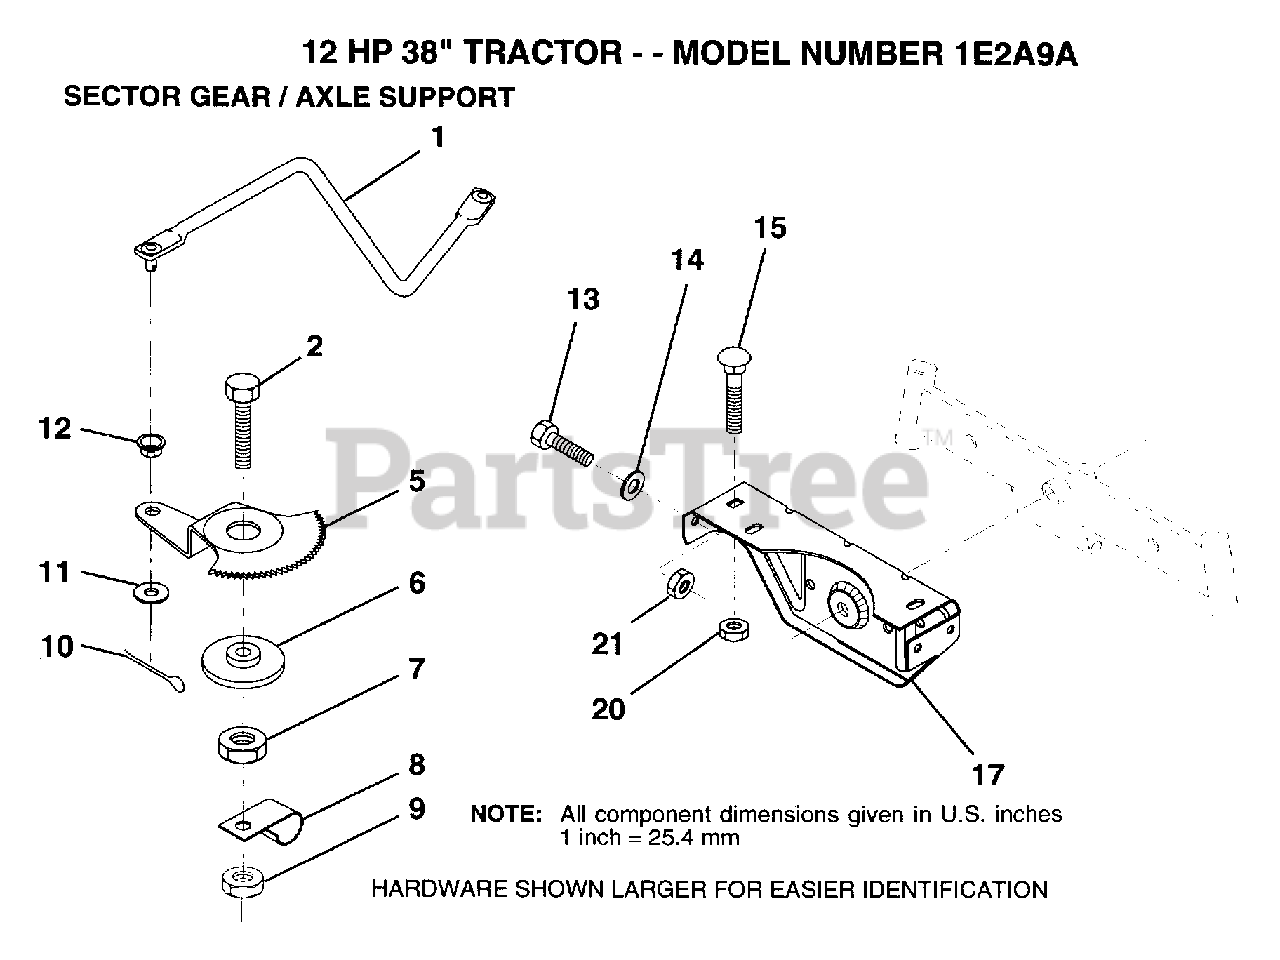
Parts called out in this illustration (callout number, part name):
1	DRAG LINK
2	"BOLT,HEX"
5	GEAR SECTOR
6	BUSHING
7	NUT
8	CLIP INSULATOR
9	NUT LTV
10	COTTER PIN
11	WASHER
12	BUSHING.DRAGLINK
13	BOLT
14	WASHER
15	BOLT
17	SUPT AXLE FRONT
